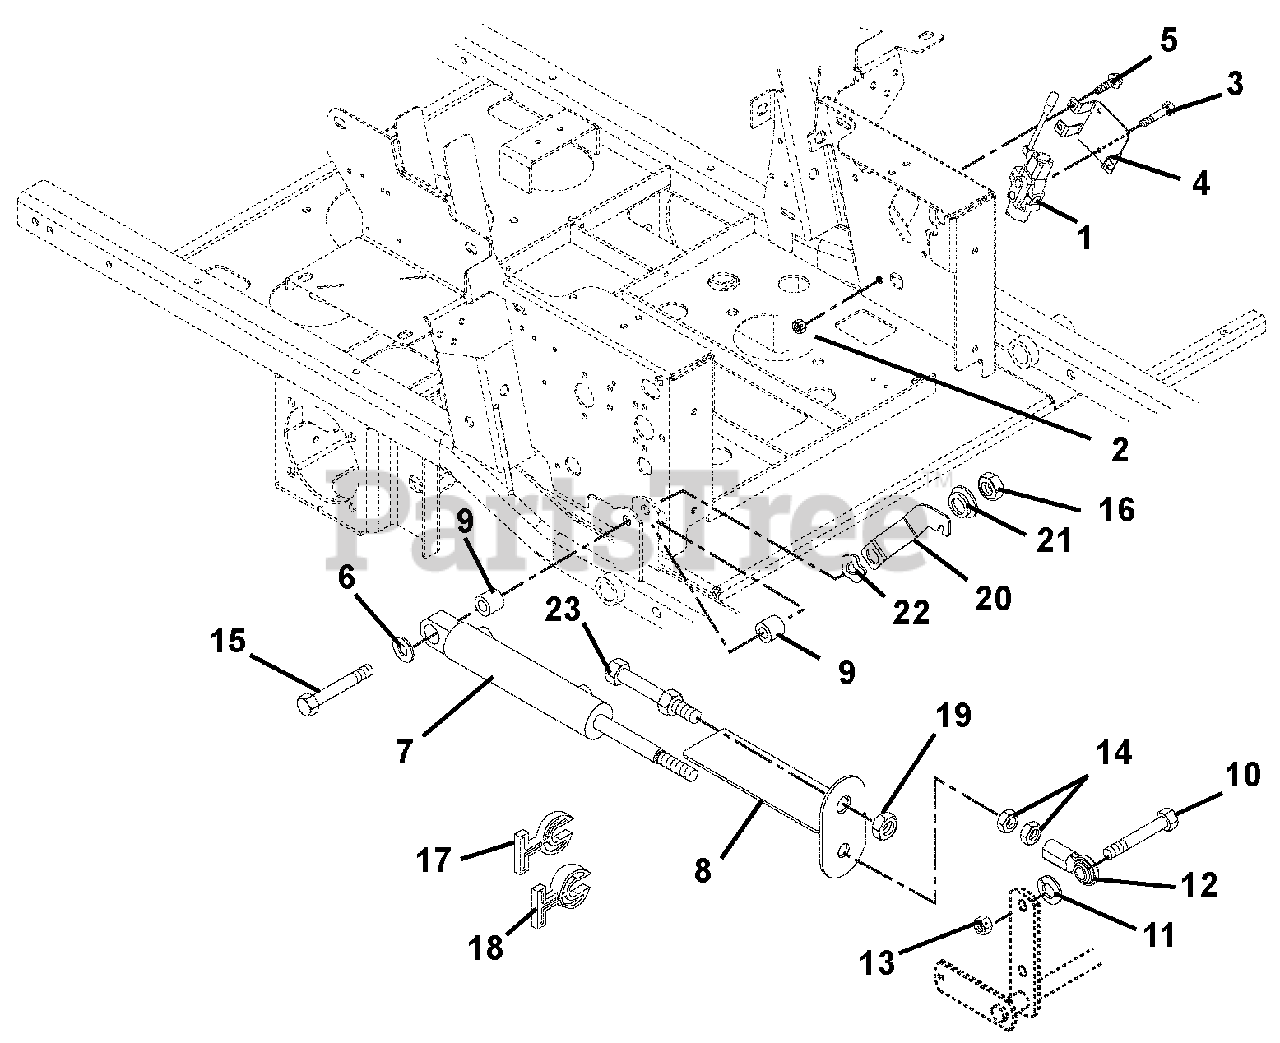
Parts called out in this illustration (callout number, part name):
1	Valve, Hydraulic
2	Nut, Locking Top Flange .31-18
3	Bolt, Hex .31-18 x 2.5 Grade 5
4	Bracket, Valve Mounting
5	Screw, Tapping .38-16 x .50 Hex Washer Head
6	Washer, Flat Steel .515 x 1.625 x .25
7	Cylinder, Hydraulic Lift
8	Strap, Cut Indicator / Guard
9	Bushing .516 x 1.00 x 1.05
10	Bolt, Hex .62-11 x 2.25 Grade 8
11	Washer, Lock .62 x .156
12	Rod End, Right Hand Female .625
13	Nut, Locking Center .62-11
14	Nut, Jam .625-18
15	Bolt, Hex .50-13 x 3.75 Grade 5
16	Nut, Locking Top Flange .50-13
17	Stop, Cylinder .34 Thick
18	Stop, Cylinder .68 Thick
19	Nut, Jam .75-16
20	Latch, Footboard
21	Bushing, Flange .515 x .75 x .275 x 1.12
22	Washer, Wave .076 x 1.12 x .08
